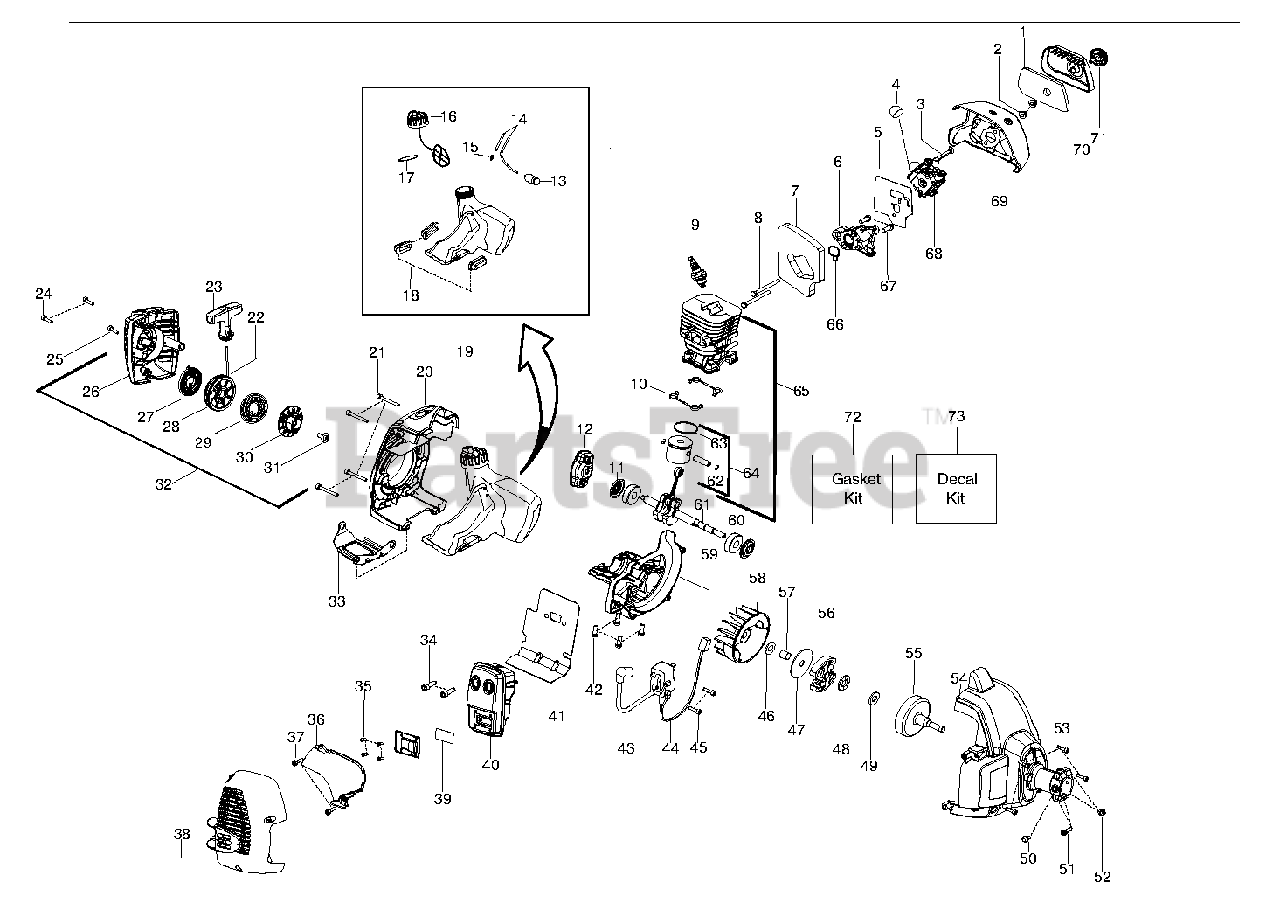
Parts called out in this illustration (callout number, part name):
1	FILTER AIRBOX
3	CHOKE LEVER
4	PURGE BULB ZAMA
5	KIT GASKET CARB 28CC
6	CARB ADAPTOR
7	KIT GASKET 28CC
8	BOLT CARB ADAPTOR
10	KIT GASKET 28CC
11	KIT GASKET 28CC
12	STARTER PAWL BRIDGE
13	FUEL PICK-UP ASSY
14	KIT-LINE(FUEL)
15	FUEL LINE FITTING
16	ASSY - FUEL CAP W/RETAINER
17	KIT GASKET 28CC
18	ISOLATOR FUEL TANK
19	KIT FUEL TANK ASSY
20	SHROUD REAR
23	HANDLE - STARTER
24	SCREW M5-0.8X30MM
25	SCREW M4 X 1.75 PT 16MM
26	STARTER HSG W/EYELET
27	KIT STARTER SPRING
28	KIT STARTER PULLEY
29	SPRING - DRIVER
30	DRIVER PULLEY
32	ASSY STARTER HSG
33	PLATE WEAR
34	BOLT MUFFLER
35	SCREW-6-19X5/16PLAST PA
36	SHIELD HEAT
37	SCREW M4 X 1.75 PT 16MM
38	KIT MUFFLER GUARD
39	KIT SPARK ARRESTOR SCREEN
40	KIT MUFFLER W/CATALYST
41	KIT GASKET 28CC
42	B0LT, C/SHAFT 36/41
43	IGNITION MODULE MBU-7
44	ASSY MODULE LEAD WIRE
45	SCREW M4 X .70 TT 16MM
46	WASHER CLUTCH
47	WASHER-CLUTCH
48	BEARING THRUST
49	WASHER THRUST
50	SCREW-10-16 X 1/2, TYPE 2
51	SCREW-10-24 X 1" (UNC)
52	LOCKNUT-HEX 10-24
53	SCREW M4 X .70 TT 16MM
54	ASSY FAN HOUSING
55	ASSY-CLUTCH DRUM
56	ASSEMBLY CLUTCH
57	SPACER FLYWHEEL
59	CRANKCASE CAST LE28
60	BEARING RADIAL BALL (6201)
61	ASSY CRANKSHAFT
62	WRIST PIN RET.
63	RING PISTON
64	KIT - PISTON
65	KIT PISTON CYL
66	KIT GASKET 28CC
67	B0LT, C/SHAFT 36/41
68	KIT CARB
69	AIRBOX BLACK
70	COVER AIR BOX
71	ASSY - AIR BOX KNOB
72	KIT GASKET 28CC
